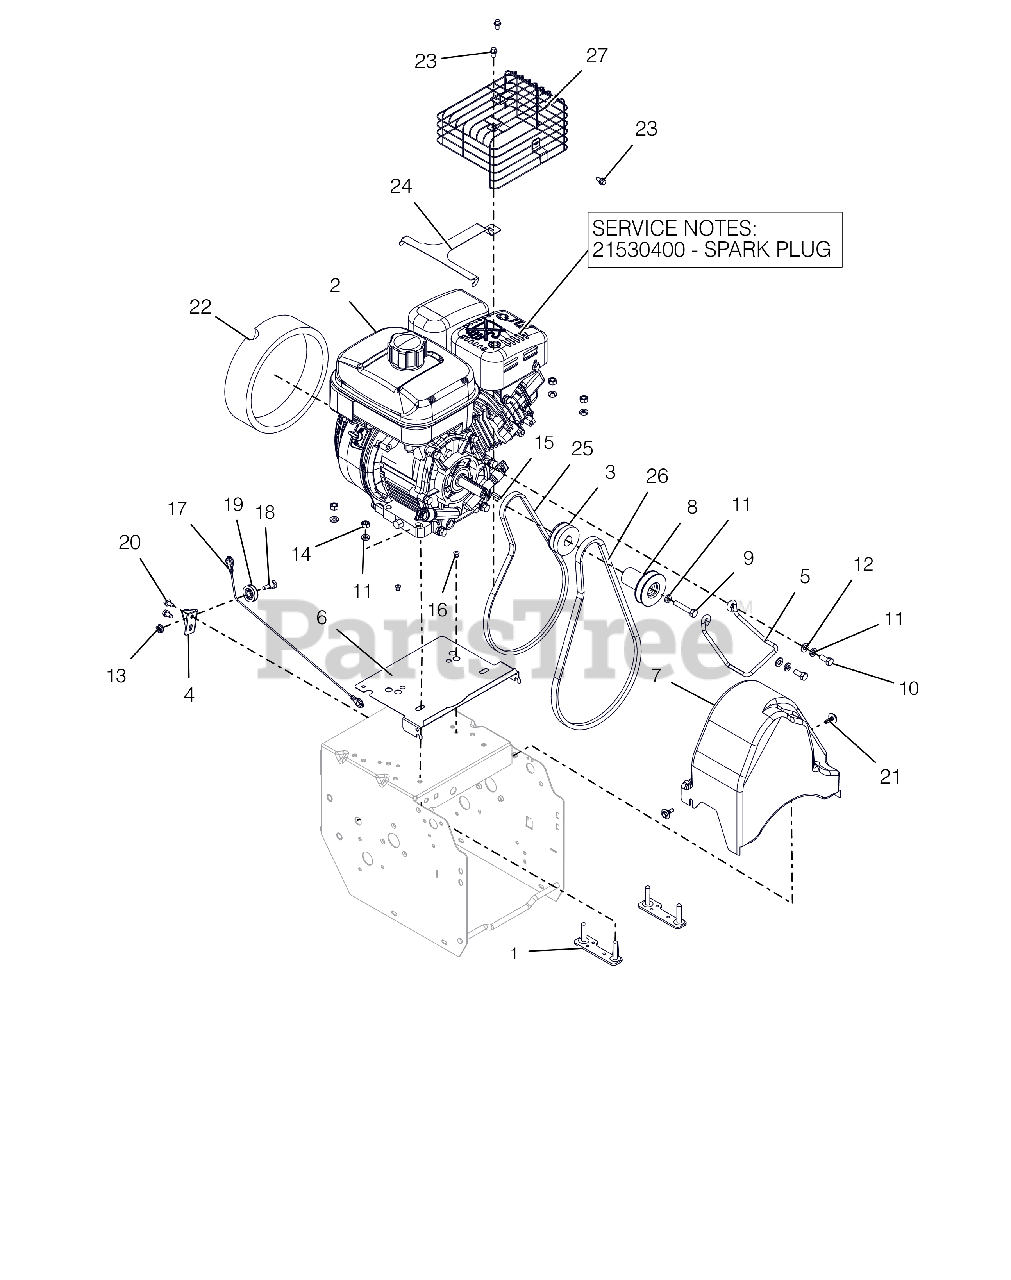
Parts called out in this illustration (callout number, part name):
1	STRAP, ENGINE BOLT-WELDMENT
2	SUBARU EX17 RECOIL ALL-SEASON
2	PLUG, SPARK - TEC. SNO-THRO
3	PULLEY, TRACTION
4	BRACKET, CABLE PULLEY
5	BELT FINGER
6	BAFFLE, COMPACT
7	BELT COVER
8	SHEAVE, AUGER DRIVE
9	@BLT-HEX .31-24X1.75 GR5 YWZC
10	BLT-HEX .31-24X.75 YWZC GR5
11	WSHR-LK .312X.097 HVY YWZC
12	@WSHR-FL-STL.344X.688X.065YWZC
13	@NUT-LK-CTR-FLG .25-20 YWZC
14	@NUT-HEX .31-18 YWZC
15	KEY-SQ .188X.75X.188
16	RVT-POP .187 YZ
17	CABLE, LOWER TRACTION (CMPCT)
18	BOLT, SHLDR-.375X.375X.25-20
19	PULLEY, CABLE
20	SCR-TAP .25-20X.50 HWH TR YWZ
21	SCR-TAP .25-20X.5 CAPTIVE
22	FOAM COVER, RECOIL-SUBARU
23	BLT-SERHFWH M6X1.0X12 8.8 CZ
24	GUARD, SNOW-SUBARU EX17
25	V-BELT, 3L-WRAPPED
26	V-BELT, HA-RAW EDGE
27	GUARD,MUFFLER,SUB 20A-37303-11
